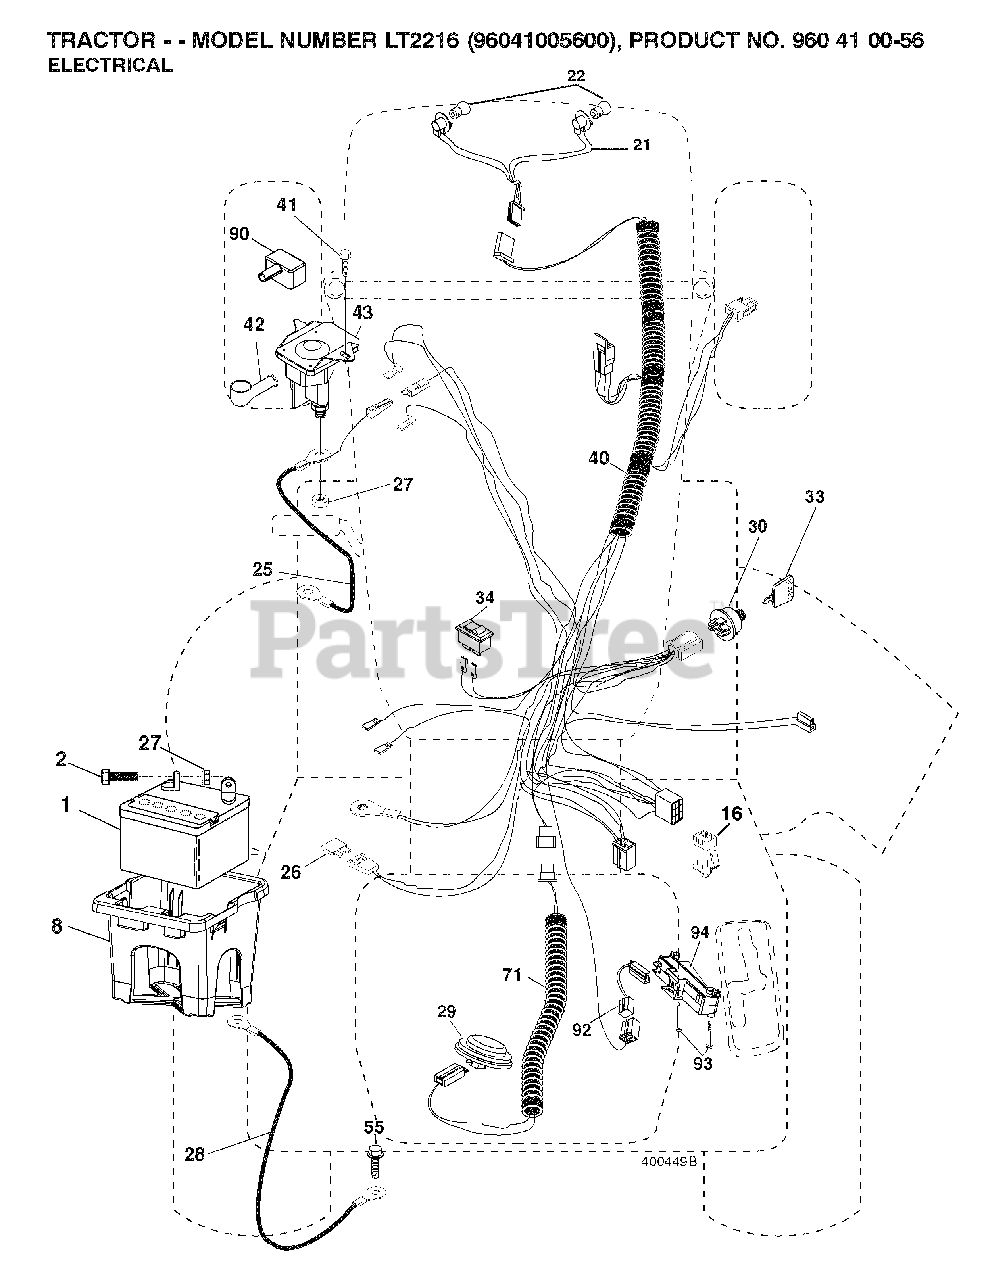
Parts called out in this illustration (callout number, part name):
1	BATTERY 12V .35 AMP
8	BOX.BATTERY.MNT.REAR.L
16	SWITCH INTERLOOK PUSH-IN
21	HARNESS ASSY LIGHT
22	LIGHTBULB
25	CABLE.STARTER.6GA.RED.
26	FUSE 20AMP
27	NUT
28	CABLE.BLACK.18"REAR.BA
29	SWITCH.SEAT.DELTA.OPC.
30	SWITCH.IGN.DELTA.W.LGH.ROS
33	KEY MLD GEN DELTA
34	SWITCH LT
40	HARNESS IGN. DASH
41	SCREW
42	TERMINAL COVER
43	SOLENOID.W/BRASS.PLUNG
55	SCREW 5/16"
71	HARNESS.IGN.CHASS.TEX.REAR.BAT
90	COVER, TERMINAL BATTERY
92	HARNESS.PIGTAIL.CONSLE
93	SCREW.PLASTITE
94	MODULE.REVERSE.ROS
